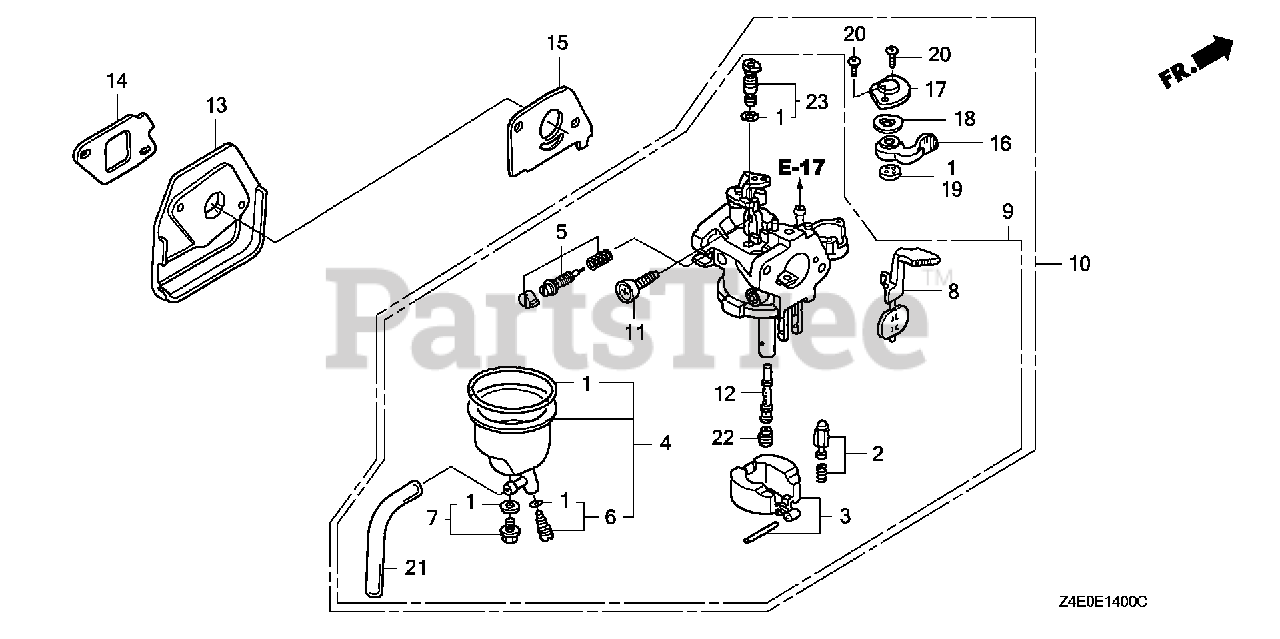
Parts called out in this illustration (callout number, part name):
1	GASKET SET
2	VALVE SET, FLOAT (SEAT NOT INCLUDED)
4	CHAMBER SET, FLOAT
5	SCREW SET, PILOT
6	SCREW SET, DRAIN
7	SCREW SET
10	CARBURETOR ASSY. (BF32F B)
10	CARBURETOR ASSY. (BF32F C)
10	CARBURETOR ASSY. (BF32H A)
10	CARBURETOR ASSY. (BF32H B)
11	SCREW, THROTTLE STOP
12	NOZZLE, MAIN
13	INSULATOR, CARBURETOR
14	GASKET, INSULATOR
15	GASKET, CARBURETOR
16	LEVER, PETCOCK
17	PLATE, LEVER SETTING
18	SPRING, PETCOCK LEVER
19	GASKET, PETCOCK
20	SCREW, PAN (3X6)
21	BULK HOSE, VINYL (3.5X6.5X8000) (3.5X6.5X100)
22	JET, MAIN (#55)
22	JET, MAIN (#58)
22	JET, MAIN (#60)
23	JET SET, PILOT (#35)
